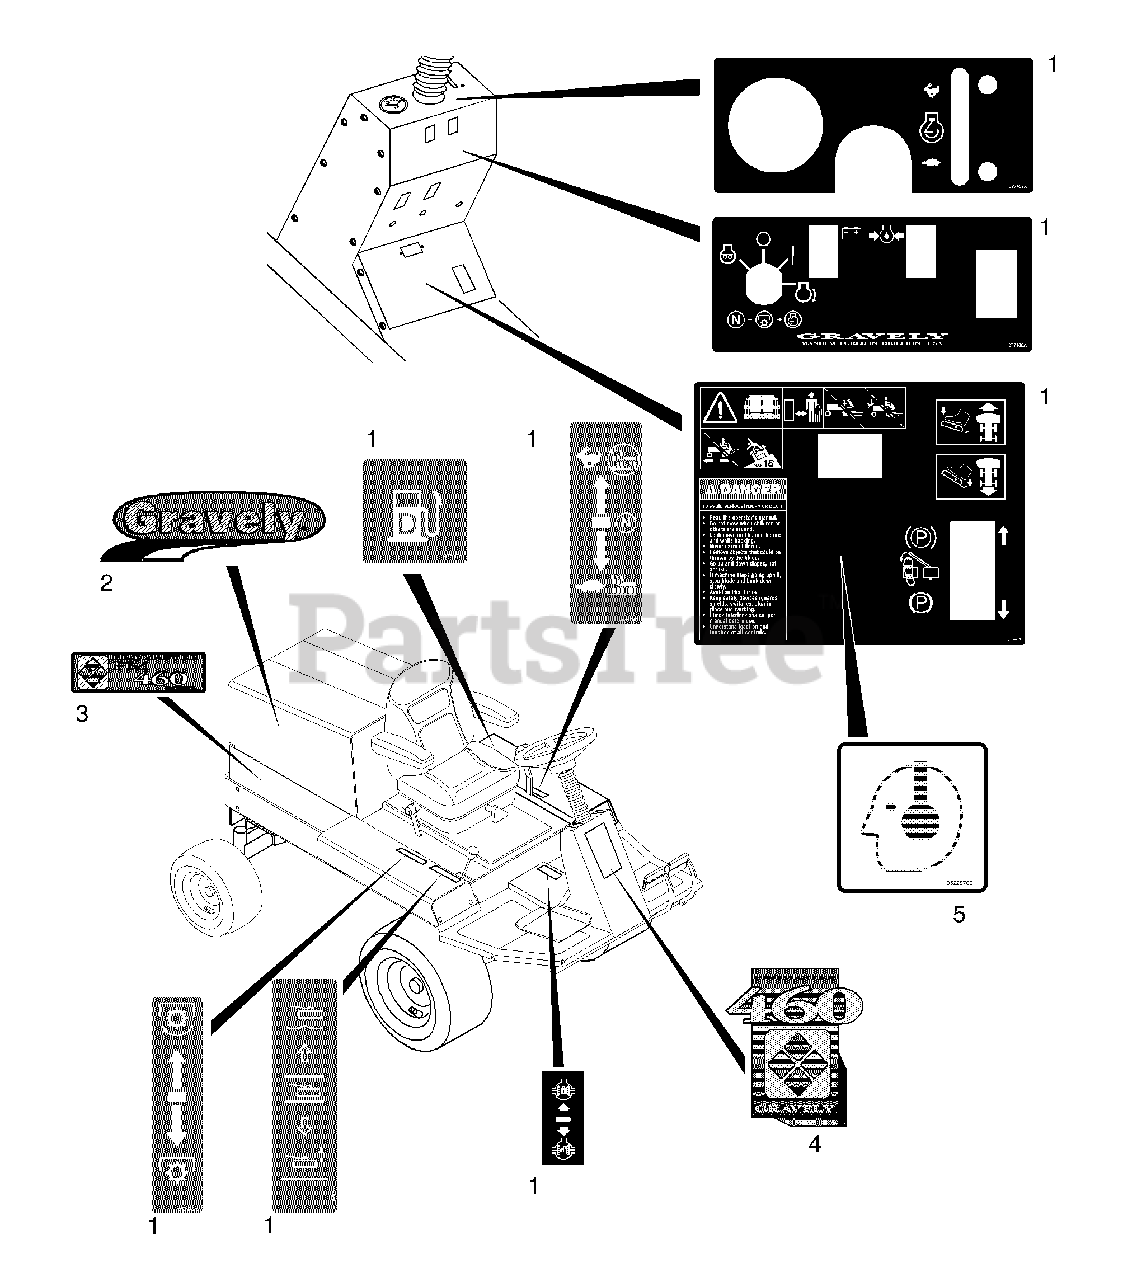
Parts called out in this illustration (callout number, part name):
1	Decal Set
2	Decal-Gravely Logo Right Hand
2	Decal-Gravely Logo Left Hand
3	Decal-Gravely Logo
4	Decal-Gravely Logo
5	Decal-Ear Protection
